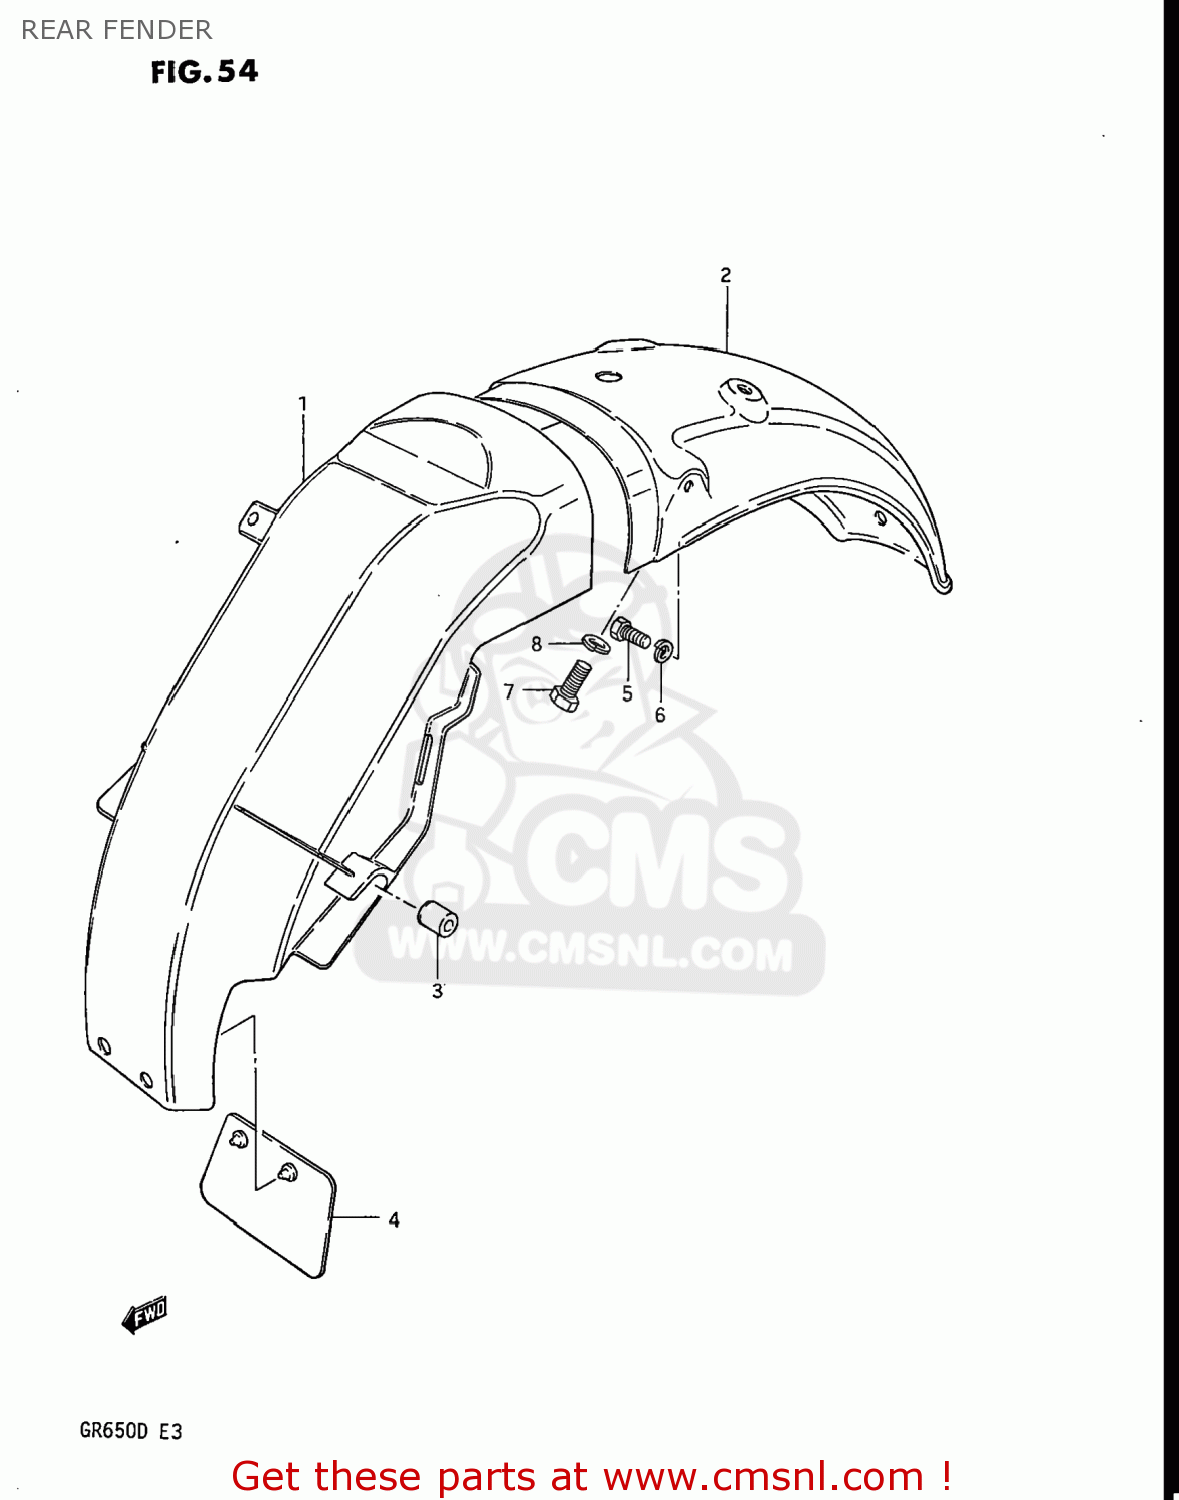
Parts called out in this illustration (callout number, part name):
1	BODY,REAR FENDER,FRONT
2	FENDER,REAR
3	CUSHION
4	GUIDE,RR FENDER MUD
5	BOLT
6	LOCK WASHER
7	BOLT
8	LOCK WASHER
